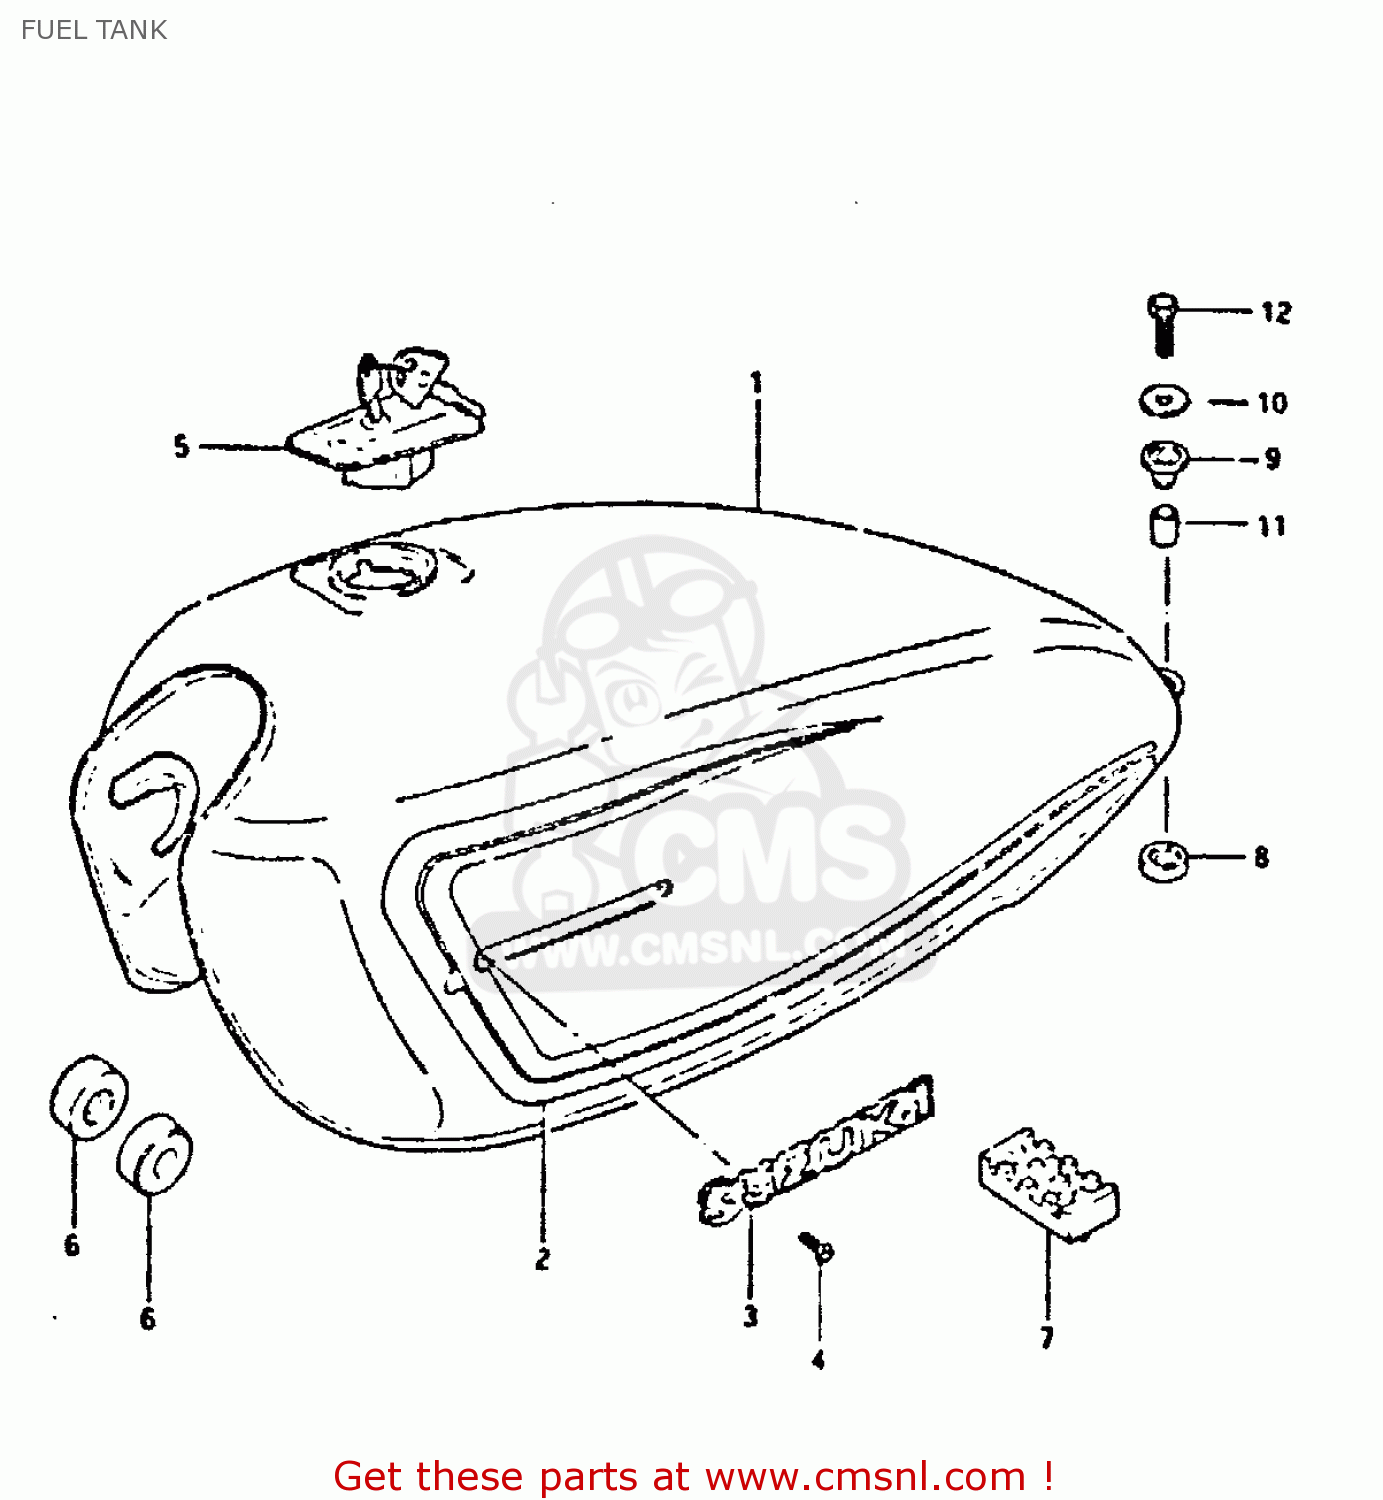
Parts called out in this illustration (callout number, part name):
1	TANK ASSEMBLY,FUEL
2	TAPE SET,FUEL TANK
3	EMBLEM
4	SCREW 3X6
5	CAP SET,FUEL TANK
6	CUSHION
7	CUSHION,FUEL TANK CTR
8	CUSHION
9	CUSHION
10	WASHER (6.5X24X1.6)
11	SPACER
12	BOLT
